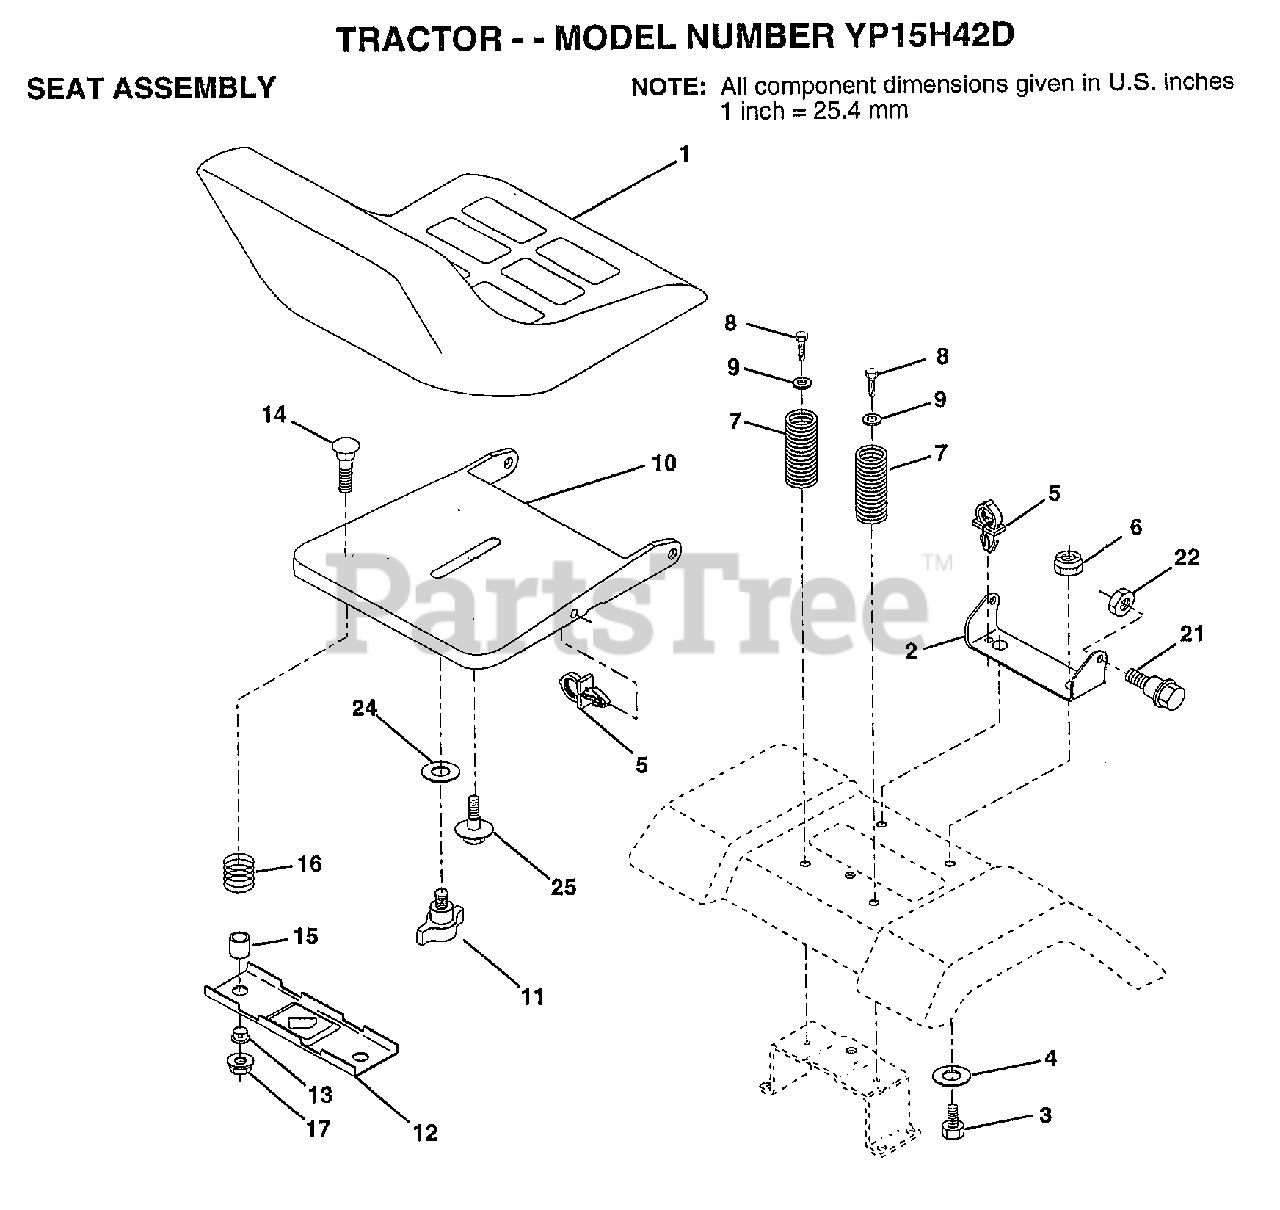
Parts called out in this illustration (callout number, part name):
1	SEAT.2400/1416.BK
2	BRACKET PVT SEAT
3	BOLT
4	WASHER PM
5	CLIP.PUSH-IN.HING
6	NUT
7	SPRING COMPRESSIO
8	SCREW GTV
9	WASHER
10	PAN-SEAT
11	KNOB.SEAT.ADJ.WINGNUT
12	BRKT SWITCH
13	BUSHING
14	BOLT-RD HD SQ NK
15	SPLIT SPACER
16	SPRING
21	"BOLT,SHOULDER"
22	NUT
24	WASHER
25	"BOLT,SHOULDER"
